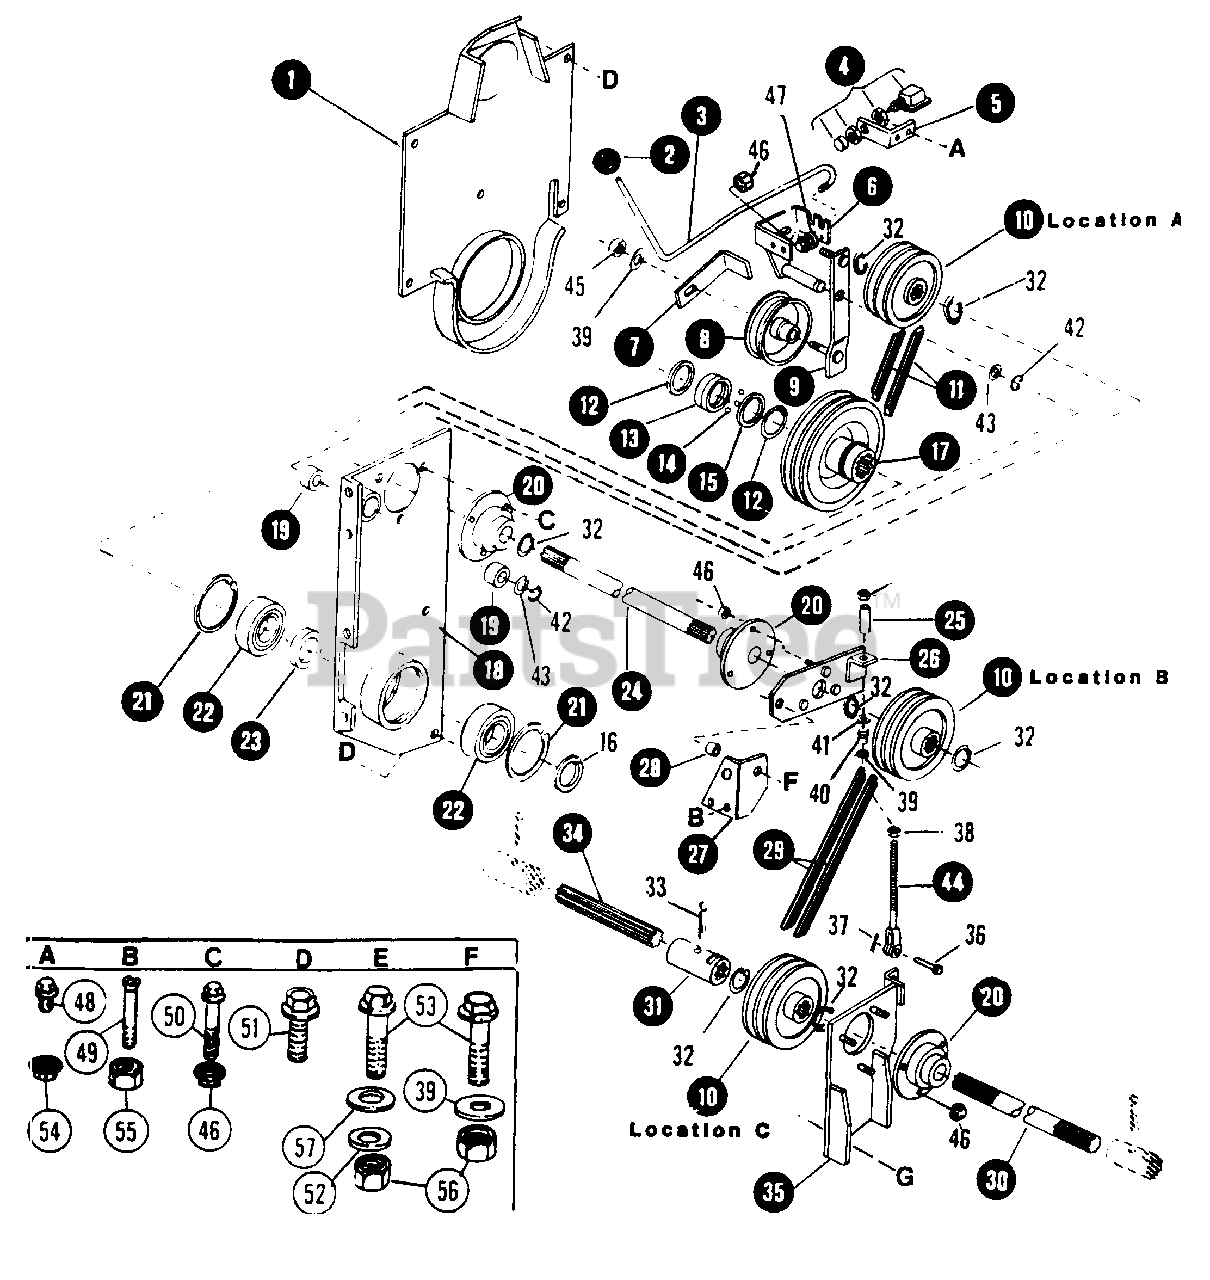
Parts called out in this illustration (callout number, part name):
1	COVER, REAR
2	KNOB, P.T.O. CONTROL LEVER
3	LEVER, REAR P.T.O. CONTROL
4	SWITCH, P.T.O. INTERLOCK
5	BRACKET, SWITCH MOUNTING
6	BRACKET, IDLER ASSEMBLY
7	GUIDE, V-BELT
8	PULLEY IDLER, 3/8" ID, 4.0" OD, 1.25" Wide
9	ARM, IDLER - ASSEMBLY
10	PULLEY, DRIVE
11	V-BELTS (SET) REAR P.T.O. DRIVE
12	RING, RETAINING
13	COLLAR, SHAFT LOCK
14	BALL, STEEL 3/8" DIAMETER
15	SPRING, SLIDING RETAINING
16	RING, RETAINING
17	PULLEY, DRIVE
18	PLATE, MOUNTING - ASSEMBLY
19	BUSHING, MOUNTING PLATE
20	BEARING, 3 Hole Flanged Lock Collar Assy., 3/4" ID
21	RING, RETAINING
22	BEARING, P.T.O. PULLEY, 1.37" ID, 2.83" OD, .66" Wide
23	SPACER, STEEL
24	SHAFT, REAR DRIVE
25	SLEEVE, ROD GUIDE
26	BRACKET, P.T O. SHAFT
27	BRACKET, PIVOT
28	SPACER, PIVOT
29	V-BELTS (SET) P.T.O. DRIVE
30	SHAFT, FRONT DRIVE
31	COUPLING, SHAFT
32	RING, RETAINING
33	COTTER-PIN, 3/32 x 3/4
34	SHAFT, REAR P.T.O.
35	BRACKET, DRIVE SHAFT
36	PIN, CLEVIS
37	COTTER-PIN, 3/32 x 3/4
38	NUT, 3/8C - SPECIAL
39	WASHER, 3/8" Flat
40	SPRING, ROD GUIDE
41	WASHER, 1/2" FLAT
42	RING, RETAINING
43	WASHER, 5/8 x 1 x .020
44	ROD GUIDE ASSEMBLY
45	NUT, 3/8C HEX FLANGE LOCK
46	NUT, 5/16C HEX FLANGE LOCK
47	SPACER, LEVER TO BRACKET
48	BOLT, 1/4C x 1/2 HEX FLANGE LOCK
49	SCREW, 1/4C x 7/8 FLAT HEAD
50	BOLT, 5/16C x 7/8 HEX FLANGE LOCK
51	BOLT, 3/8C x 3/4 HEX FLANGE LOCK
52	WASHER, 5/8 x 1-1/4 x .010
53	BOLT, 3/8C x 1-1/4 HEX FLANGE LOCK
54	NUT, 1/4C HEX FLANGE LOCK
55	NUT, 1/4C HEX
56	NUT, 3/8C HEX
57	WASHER, 3/8 x 1-1/4 x 1/8
